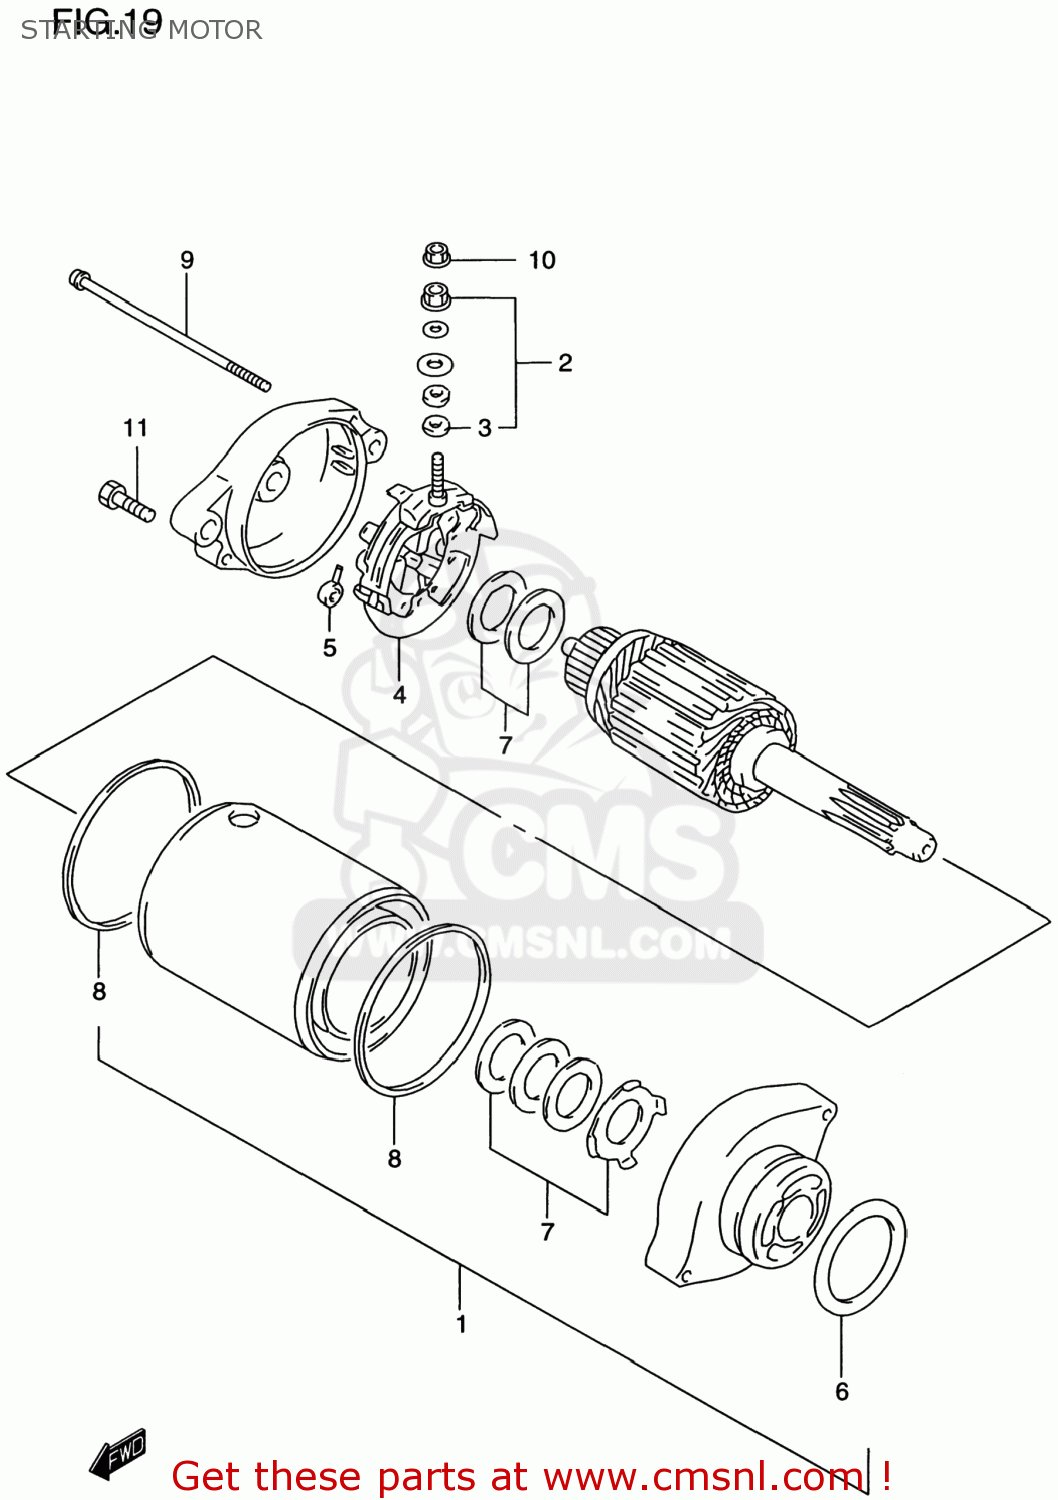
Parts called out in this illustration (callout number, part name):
1	MOTOR ASSY,STARTING
2	TERMINAL SET,BRUSH
3	O RING
4	HOLDER SET,BRUSH
5	SPRING,BRUSH
6	O RING
7	WASHER SET
8	O RING
9	BOLT
10	NUT
11	BOLT,G/S SWITC
